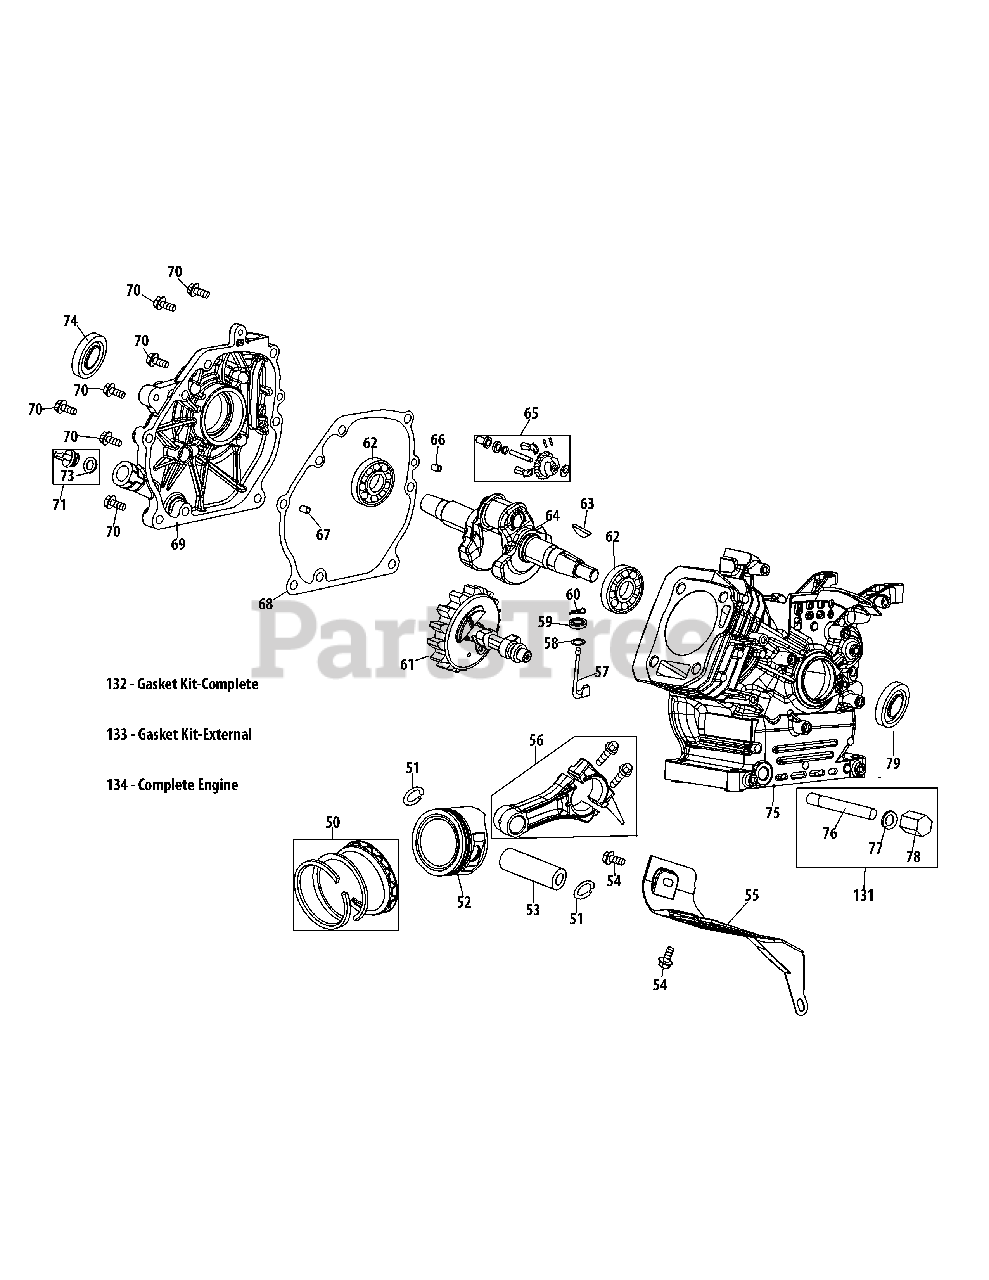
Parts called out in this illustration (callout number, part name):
50	Piston Ring Set
51	Piston Pin Snap Ring
52	Piston
53	Piston Pin
54	Bolt M6×12
55	Air Shield
56	Connecting Rod Assembly
57	Governor Arm Shaft
58	Washer 5.2×1.9
59	Governor Seal
60	Cotter Pin
61	Camshaft Assembly
62	Radial Ball Bearing, 6205
63	Woodruff Key
64	Crankshaft Kit
65	Governor Gear/Shaft Assembly
66	Dowel Pin 7×14
67	Dowel Pin 9×14
68	Crankcase Cover Gasket
69	Crankcase Cover
69	Crankcase Cover Kit
70	Bolt M8×32
71	Oil Filler Plug Assembly
73	O-Ring 15.8×2.5
74	Oil Seal, 25×41.25×6
75	Crankcase Kit
75	Short Block Assembly
76	Oil Drain Pipe
77	Washer 10×16×1.5
78	Oil Drain Plug
79	Oil Seal 25×41.25×6
131	Oil Drain Assembly
132	Gasket Kit-Complete
133	Gasket Kit-External
134	Complete Engine
